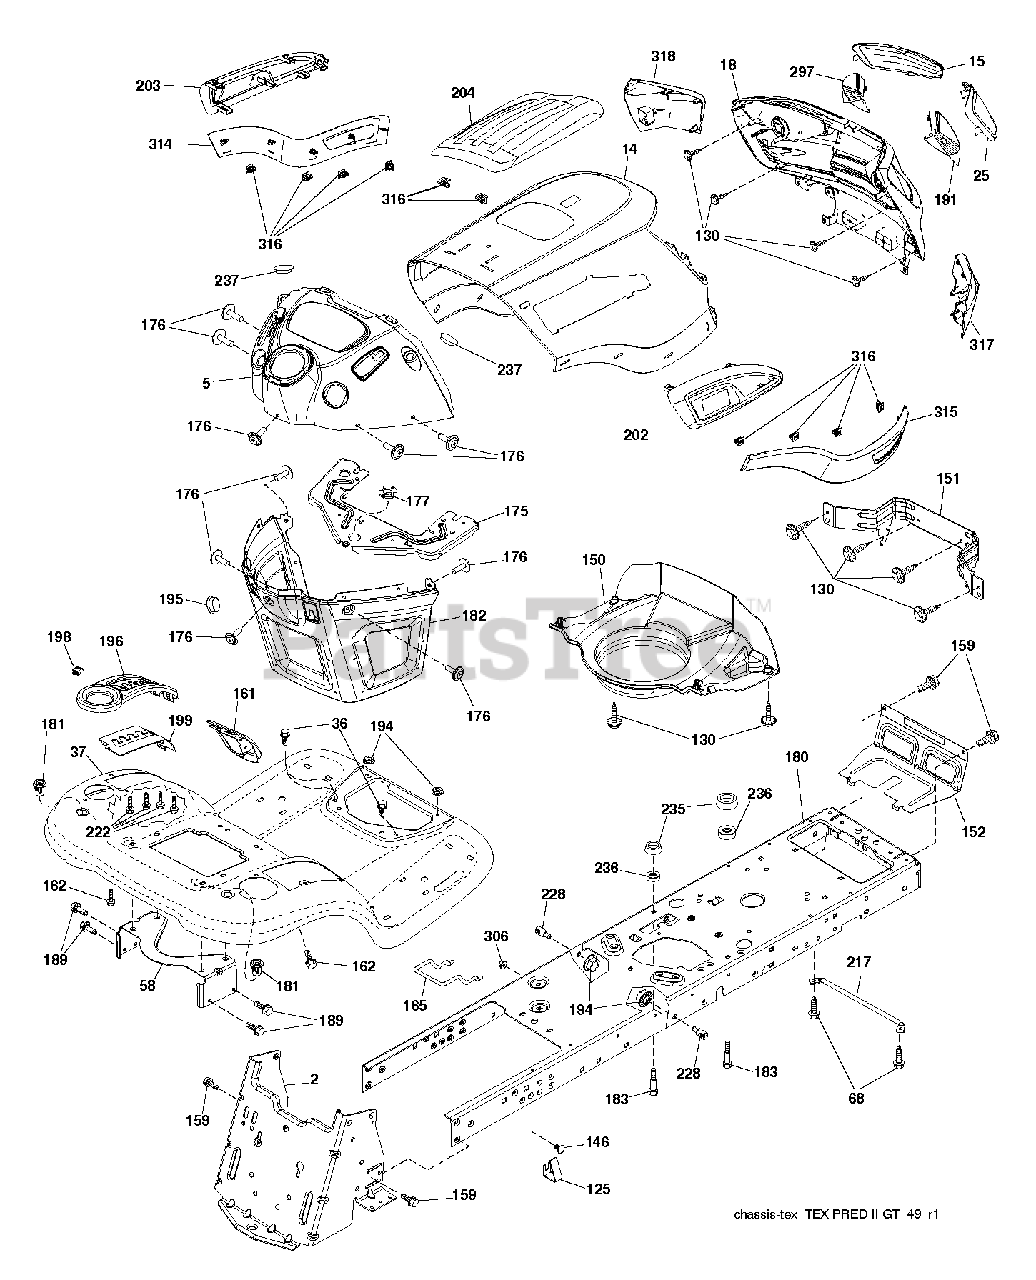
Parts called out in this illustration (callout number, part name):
2	DRAWBAR.STGT
36	SCREW 5/16"
58	BRKT.SUPPORT.FNDR/TANK
125	Fuel Line Clip
130	SCREW.#10 X 0.750.BOS THREAD
146	BOLT.RDHD.SHT.SQNK.3
150	PREDATOR.YT.GT.HOOD.A
152	SHIELD.BROWNING/DEBRIS
159	SCREW, 3/8-16X3/4
161	CONSOLE.FUEL.WINDOW.STGT.BLACK
162	SCREW.HI-LO.CONSOLE
165	SUPPORT.TANK.REAR.B/TE
175	PLATE.CROSSMEMBER.HUSQ
176	SCREW.#10-24X5/8.RN.QU
177	BUSHING STEERING
180	CHASSIS.TEX.BOLTED
181	BUSHING.MNT.FEND.CRGO.TEX.49
182	DASH.LOWER.COMMON.12V.ADAPTOR
183	BOLT.5/16-18X1-1/4 FULL THD
189	SCREW
194	NUT LOCK HEX FLANGE 5/16-18
195	PLUG.HOLE.DASH.LOWER.12V.BLK
198	INDICATOR.DECK.LIFT.RED
199	PLATE DECK LIFT
202	VENT.SIDE.RH.PRED2.GTYT.JONS
203	VENT.SIDE.LH.PRED2.GTYT.JONS
217	ROD.PIVOT.HOOD
222	SCREW.1/4-20X5/8
228	STUD.FASTNER.W/ANTI-ROTATE
235	SPACER FENDER
236	NUT.CENTERLOCK.5/16-
237	PLUG.MOUNT.CARGO.BLK
306	NUT LOCK FLG 3/8-16 UNC
315	TRIM.SIDE.GT/PRED2.RH.52
